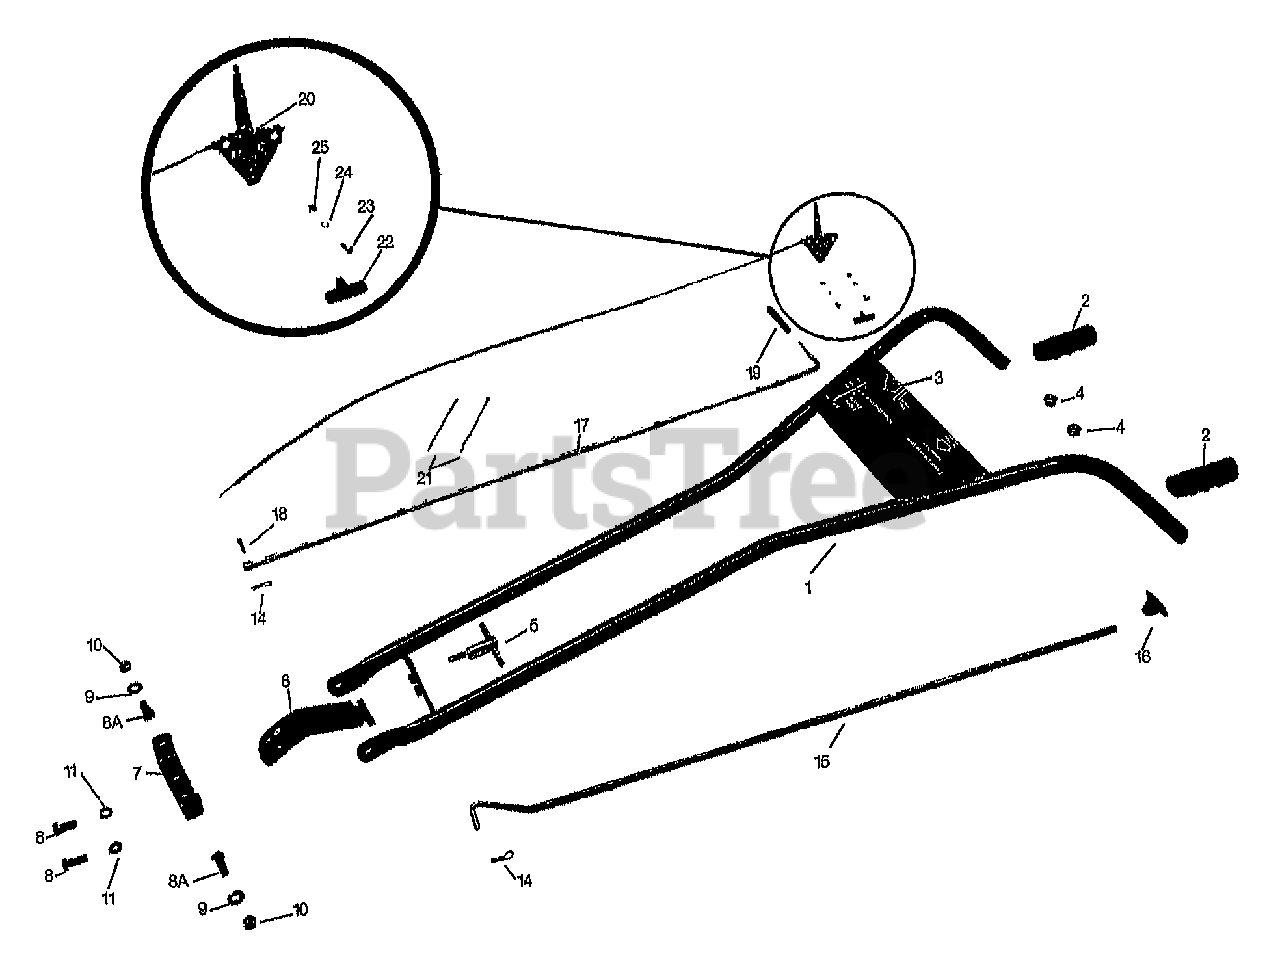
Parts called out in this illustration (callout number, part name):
1	ASSM-HANDLEBAR (INCL. 2-5)
2	GRIP-HANDLEBAR
3	DECAL-CONTROL PANEL
4	GROMMET-PLASTIC (PART OF OPERATOR CONTROL PANEL)
5	ASSM-CLAMP
6	PLATE-HANDLEBAR ADJUST
7	BRKT-HANDLEBAR MTG
8	SCR-HH 3/8-16X1.0 G5 ZP
8A	SCR-HH 3/8-16X1.0 G5 ZP
9	WASHER-FLAT 3/8 SAE
10	NUT-LOCK 3/8-16 NYLON ZP
11	WASHER-LK .375 @ DEPL
14	PIN-CLIP .08
15	ASSM-DRIVE CNTL ROD (INCL. KNOB #9208)
15	ASSM-DRIVE CNTL ROD (#9208 KNOB NOT INCL.)
16	KNOB-DRIVE CNTRL ROD
17	ROD-CONTROL
18	PIN-CLEVIS .183X1.0 ZP
19	GRIP-CONTROL ROD
20	CABLE-THROTTLE (INCL. #22 ONLY)
21	TIE-RED (TO SECURE THROTTLE CABLE TO HANDLEBARS)
22	KNOB-THROTTLE CABLE
23	SCR-RH M10-32X.5 MACH
24	WASHER-LK M10
25	NUT-HH M10-32X.125
